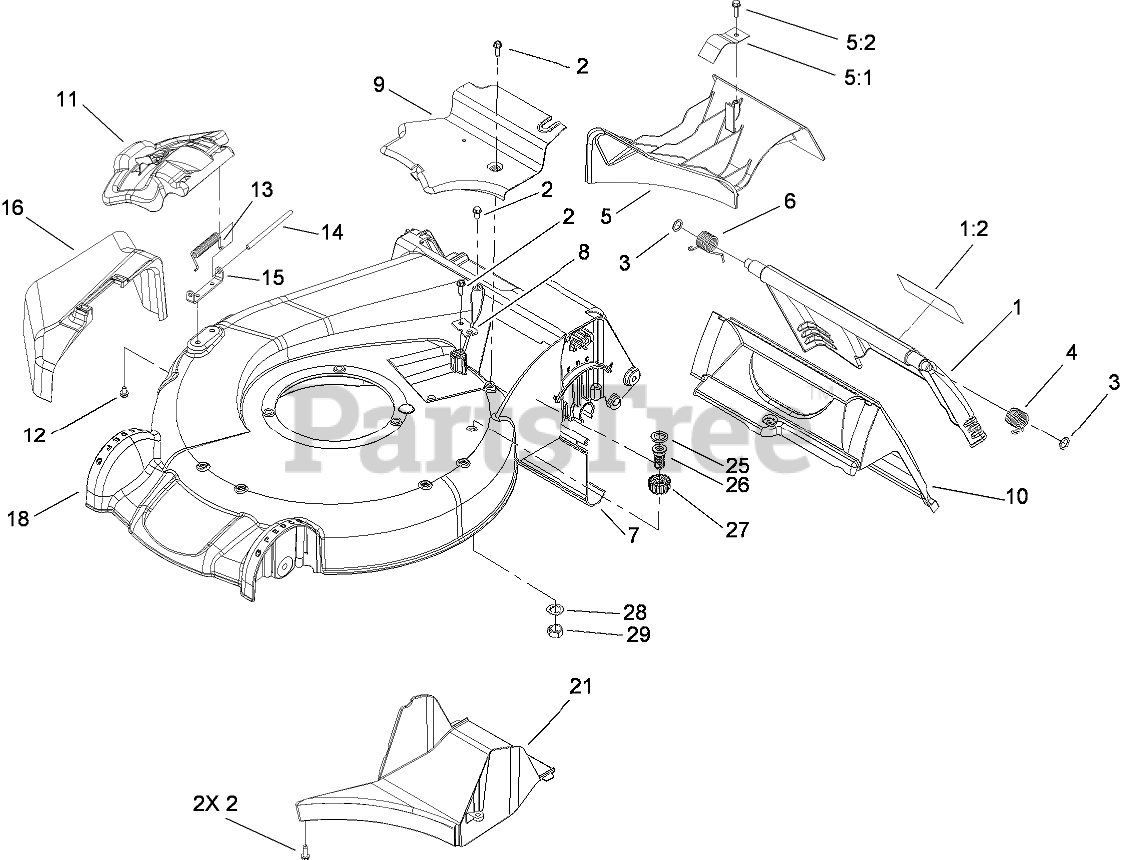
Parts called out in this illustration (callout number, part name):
1	REAR DOOR ASM
1:2	DECAL-WARNING
2	SCREW-HWHTF
3	WASHER-NYLON
4	SPRING-TORSION
5	PLUG-MULCH ASM
5:1	TAB-SPRING
5:2	SCREW-HWH
6	SPRING-TORSION
7	SHIELD-TRAILING
8	BRACKET-CABLE, TRACTION
9	COVER-BELT
11	DISCHARGE DOOR ASM
12	SCREW-HWH
13	SPRING-TORSION
14	ROD-COVER
15	BRACKET-COVER
16	CHUTE-DISCHARGE, SIDE
18	HOUSING ASM
21	TUNNEL-DISCHARGE
25	WASHER-SEAL, WASHOUT PORT
26	PORT-WASHOUT
27	COUPLING-HOSE, WASHOUT PORT
28	WASHER-TOOTH, INTERNAL
29	NUT-JAM
